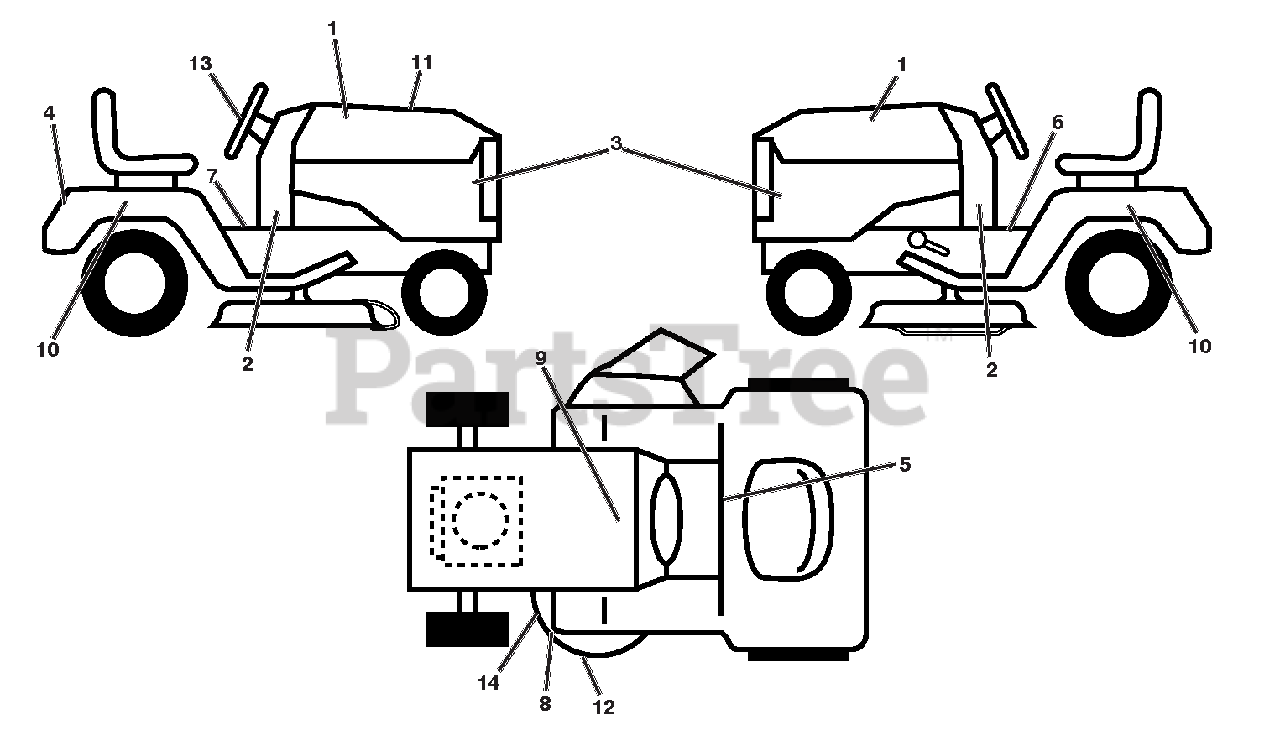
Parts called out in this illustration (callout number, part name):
1	DECAL.HOOD.RH.PRECISION.ARIENS
2	DECAL.DASH.LOWER
3	DECAL.SDPNL.PWRDBY KOHL.ARIENS
4	DECAL.FENDER.REAR.ARIENS
5	Decal, Flag
6	DECAL, WARNING START INST.
7	DECAL.FENDER
8	DECAL.MOWER.WARN.KEEP HAND AWY
9	DECAL.BAT.DAN/POI P/L SYM.WPN
10	DECAL.FENDER.SIDE.HYDRO.ARIENS
11	DECAL.RPL.KH.TWIN.TLW.54.0510
12	DECAL.MOWER.SCH.48/54.PREM.
13	DECAL.WHEEL.STEER.ARIENS
14	DECAL.MOWER.CAUTION.TENSION.AR
